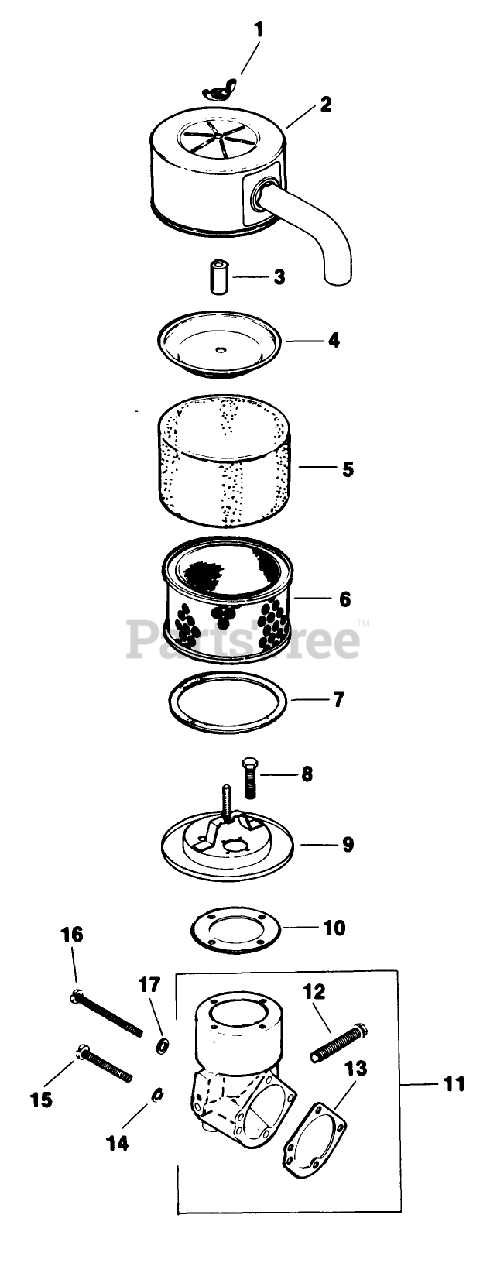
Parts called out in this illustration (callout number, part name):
1	Nut-Wing
2	Cover-Air Cleaner
4	Cover-Inner
5	Element
6	Element
7	Seal
8	Screw-H.C.
9	Base-Air Cleaner
10	Gasket-Air Cleaner
11	Kit-Elbow (Incl. Ref. #12 13)
12	Screw-H.C
13	Gasket-Elbow
14	Washer
15	Screw-R.H.M.
16	Screw-R.H.M.
17	Washer
